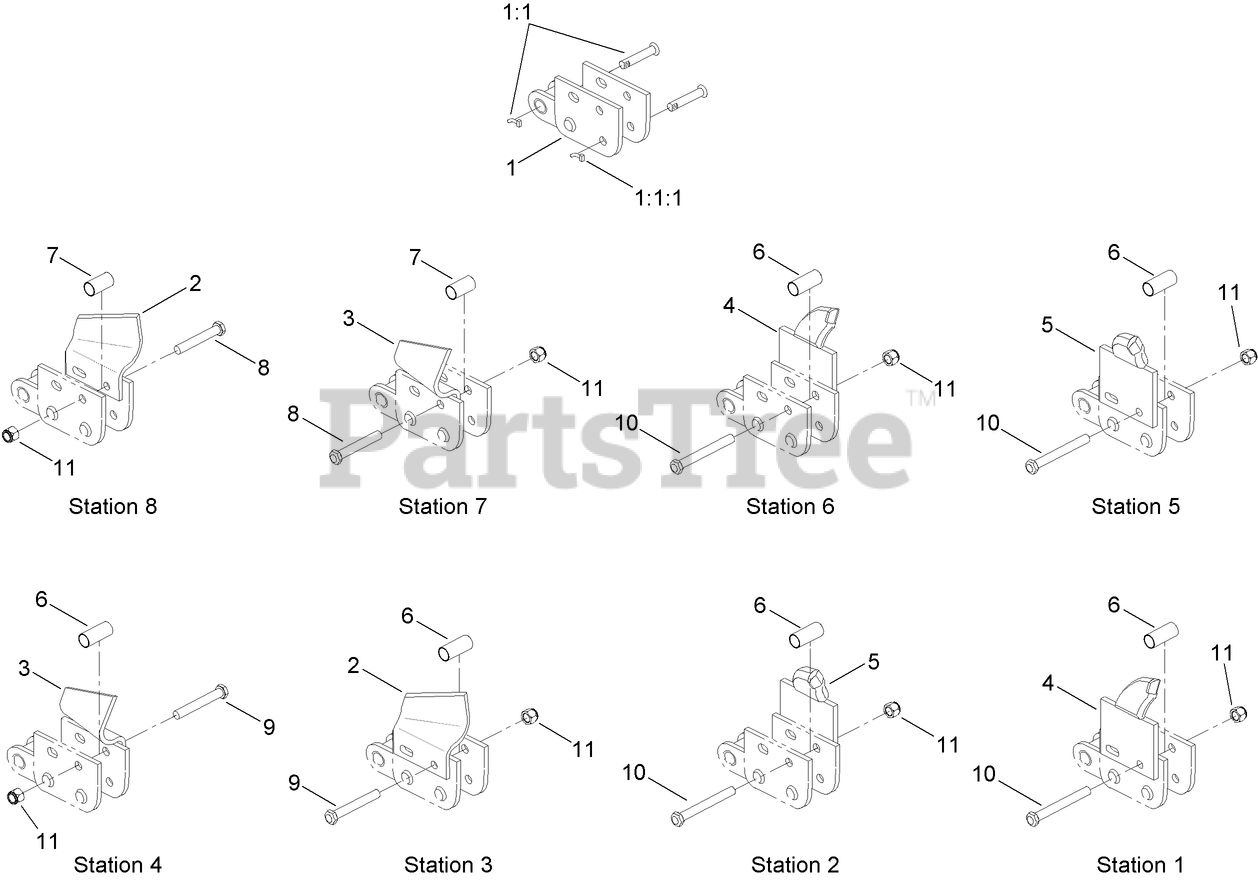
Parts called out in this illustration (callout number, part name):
1	CHAIN REPAIR LINK ASM
1:1	NOTCHED PIN AND KEEPER ASM
1:1:1	PIN-KEEPER
2	CUTTER-CUP, LH
3	CUTTER-CUP, RH
4	TOOTH-TERMINATOR, LH
5	TOOTH-TERMINATOR, RH
6	SPACER-TUBE, OUTSIDE MOUNT
7	SPACER-TUBE, INSIDE CUP MOUNT
8	BOLT-HH
9	BOLT-HH
10	BOLT-HH
11	NUT-LOCK
